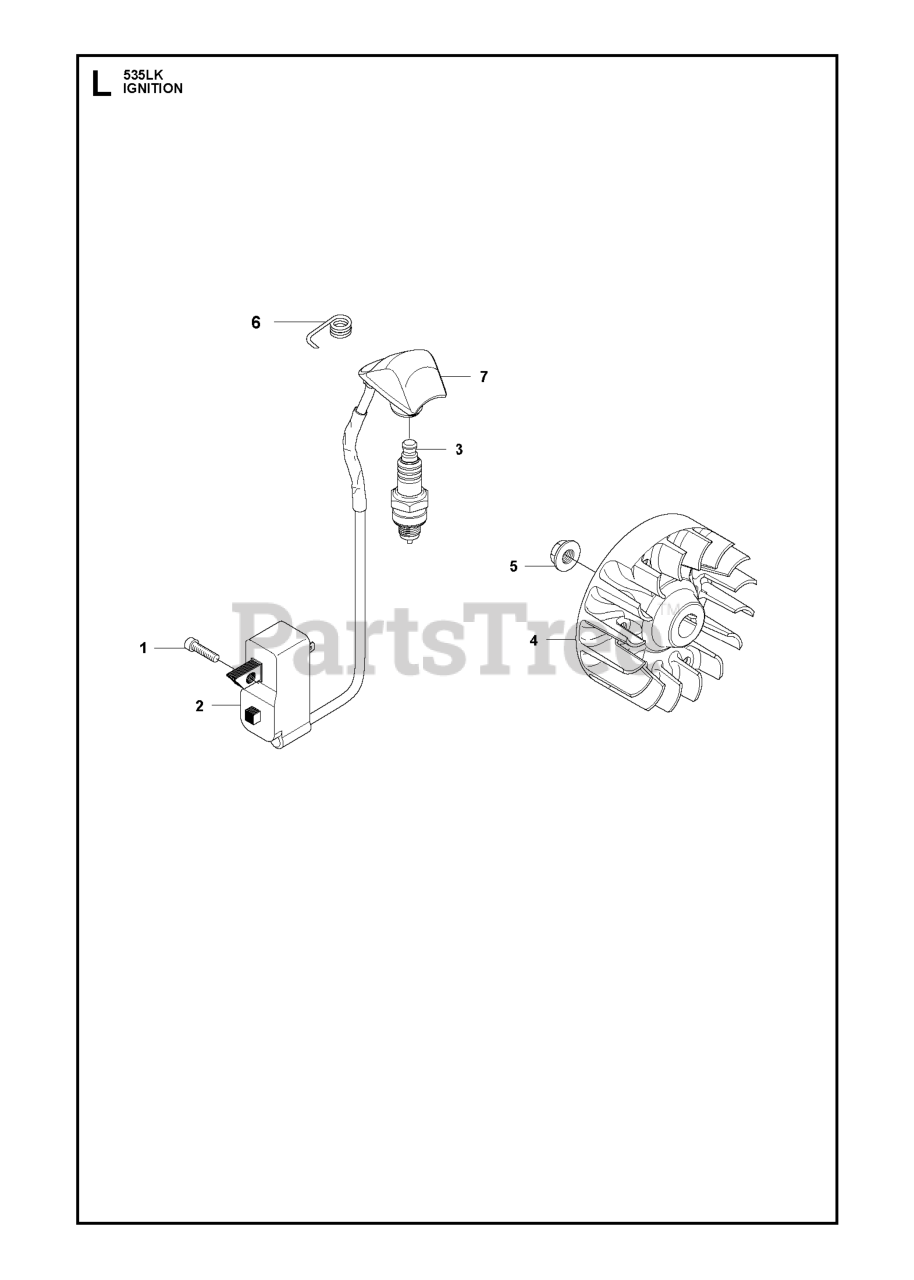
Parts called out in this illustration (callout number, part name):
2	IGNITION MODULE OPS
3	SPARK PLUG RCJ6Y NLA
4	FLYWHEEL
5	FLANGE NUT
7	SPARK PLUG CAP
